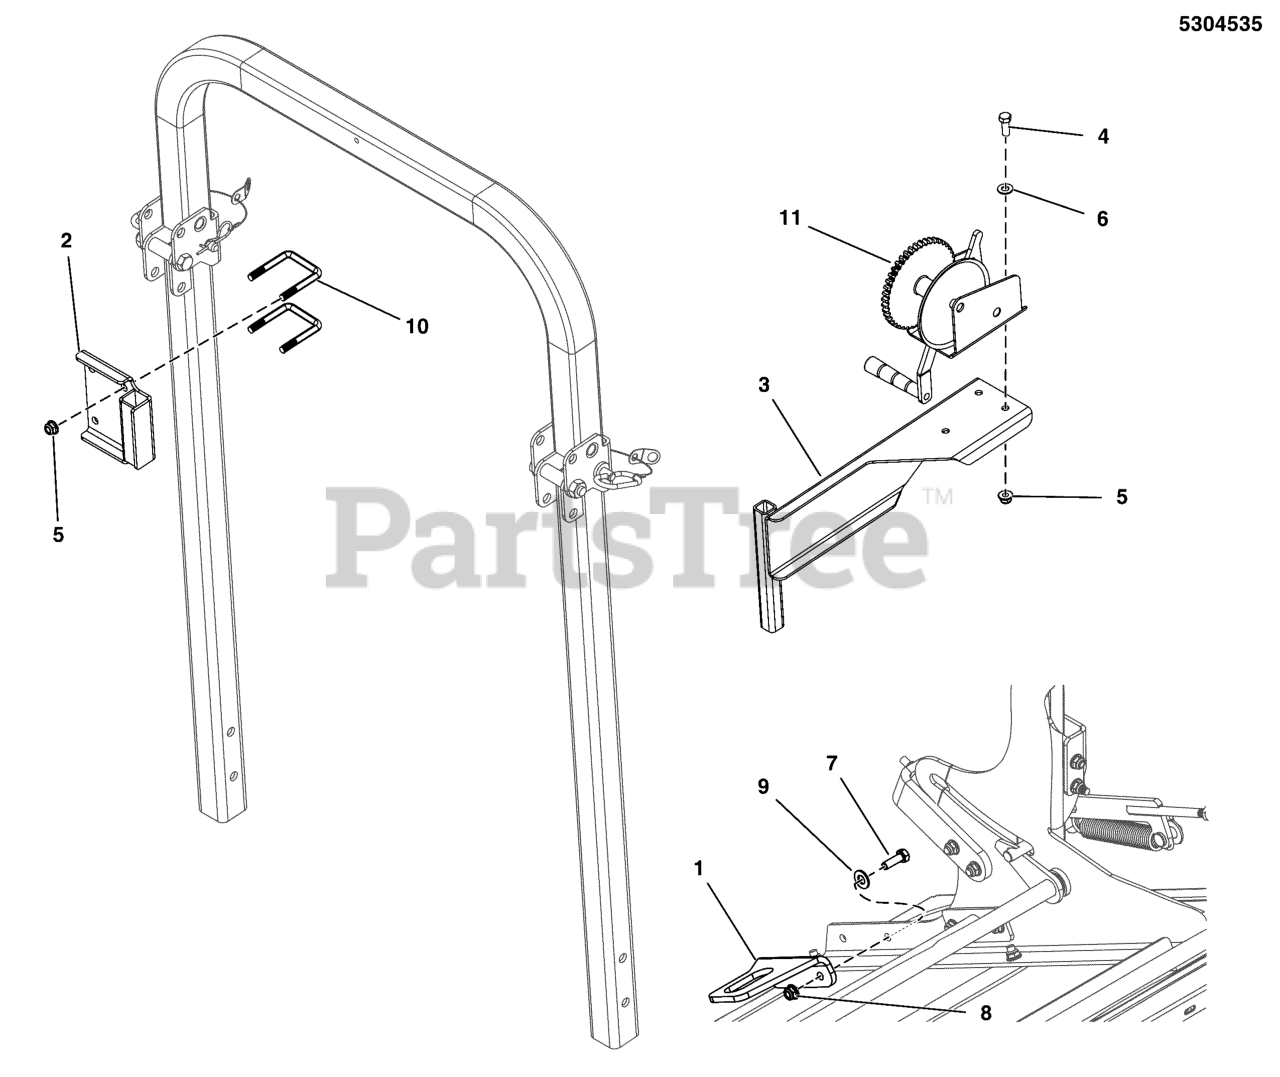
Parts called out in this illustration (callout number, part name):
1	BRACKET, ANCHOR, WINCH - BLK
2	WELD, QUICK MOUNT, WINCH - BLK
3	WELD, ASSY, WINCH BASE - BLK
4	BOLT, 3/8-16 X 1" GD5 CZ
5	NUT, 3/8-16 HEX NYLOCK FLANGE
6	WASHER, 3/8 SAE
7	BOLT, 5/16-18 X 1 GD5 CZ
8	NUT, 5/16-18 HEX NYLOCK FLANGE
9	WASHER, 5/16" SAE
10	U-BOLT, SQR, 3/8 X 2 X 2-5/8, CZ
11	KIT, HOPPER WINCH, ZTR
